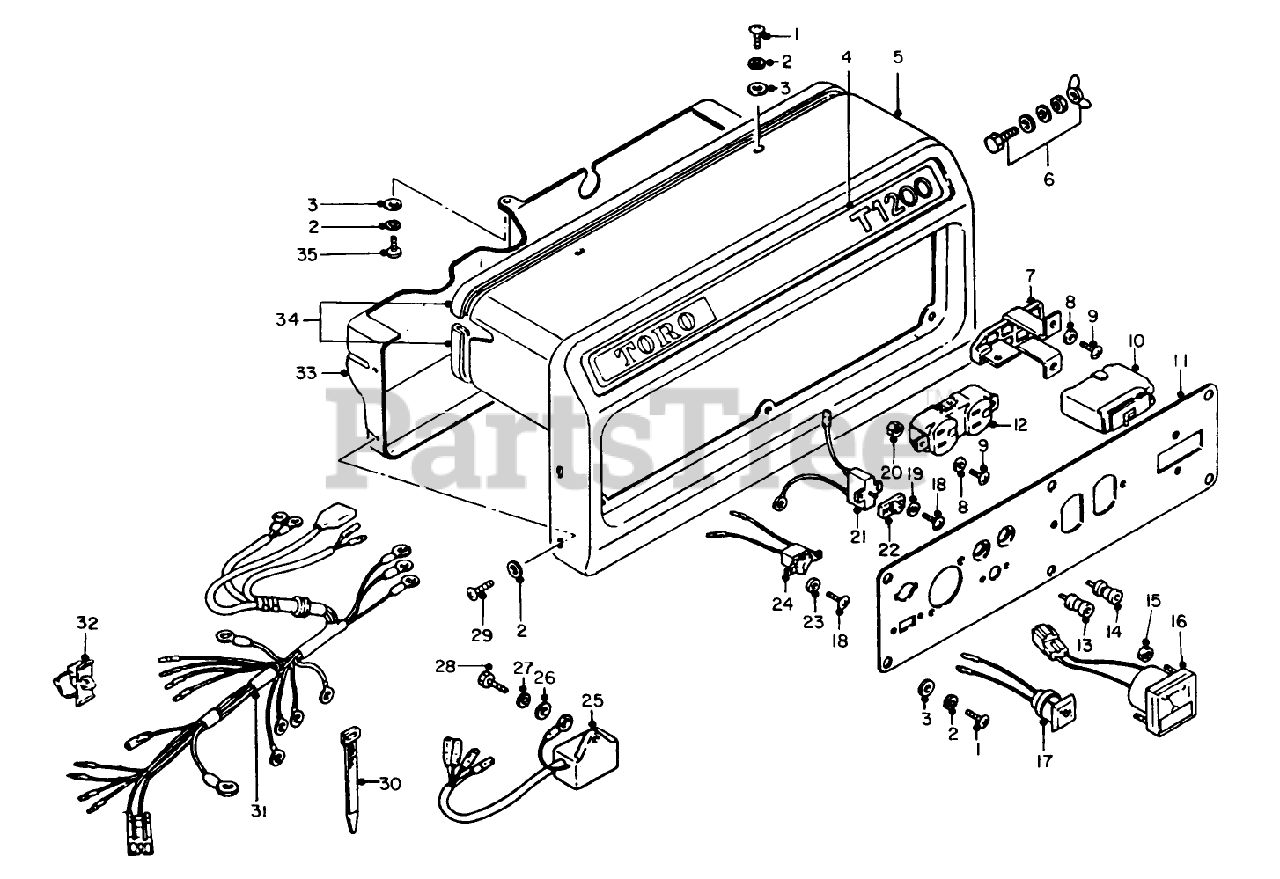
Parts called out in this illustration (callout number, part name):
1	SCREW
2	Washer
3	WASHER
4	Emblem-Toro
5	Panel-Control
6	GROUND TERMINAL
7	BREAKER HOLDER
8	Washer
9	Screw
10	Circuit Breaker
11	PLATE
12	RECEPTACLE
13	TERMINAL-
16	Meter-Voltage
18	Screw
19	Washer-Lock
21	Circuit Breaker DC
23	Washer
24	Switch
25	OIL LEVEL UNIT
26	Washer
27	LOCKWASHER
29	Screw
30	Clamp
31	CONTROL HARNESS
32	Clamp
33	Panel-Rear
35	Screw
